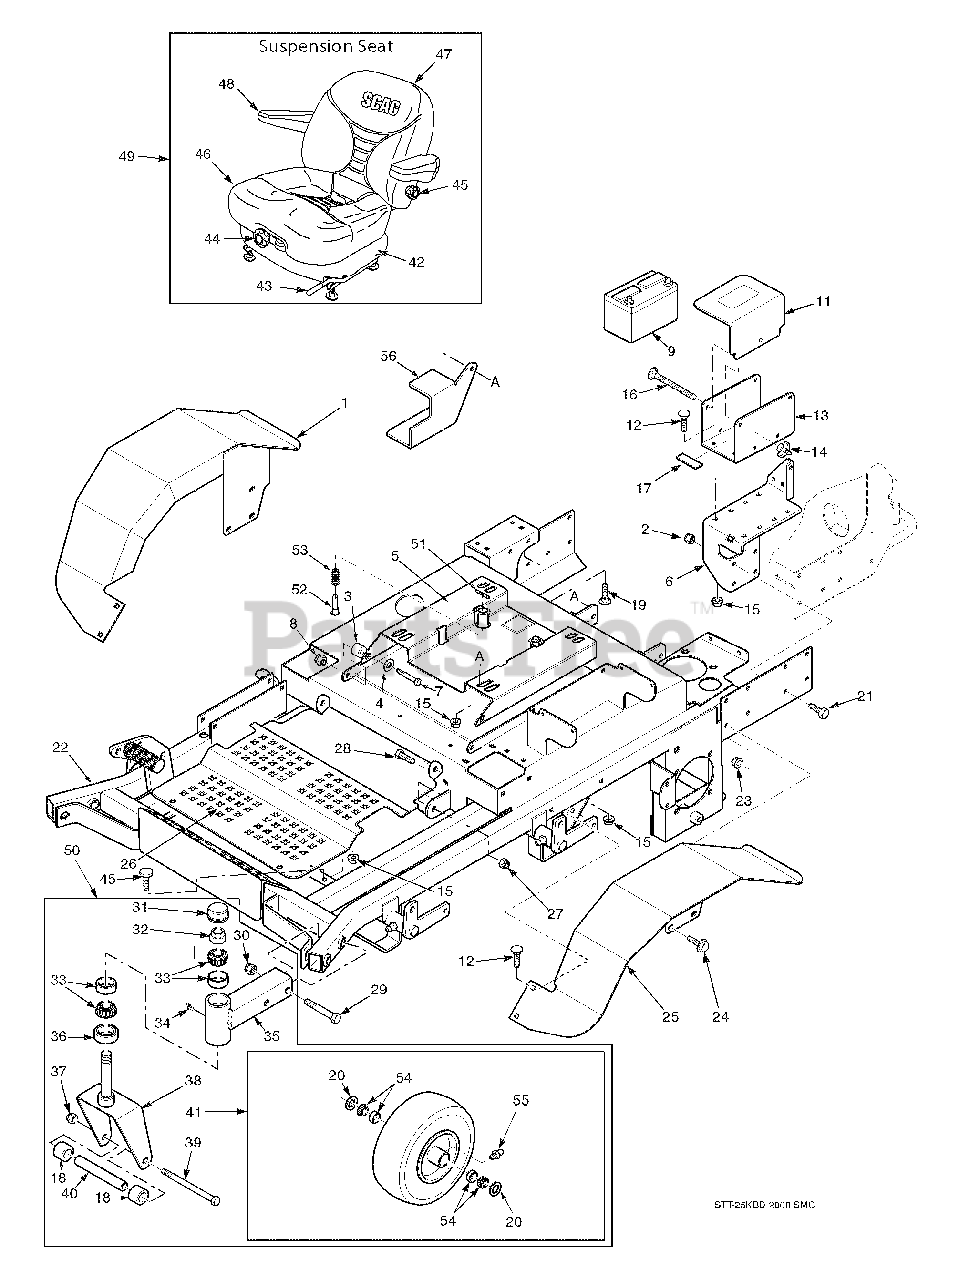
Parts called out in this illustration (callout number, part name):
1	Fender Weldment, RH
2	Nut, Elastic Stop 3/8-16
3	Spacer
4	Flatwasher, 3/8-.391 x .938 x .105
5	Seat Plate Weldment
6	Battery Box Mount
7	Bolt, Hex Head 3/8-16 x 2.0"
8	Nut, Elastic Stop 3/8-16
9	Battery
10	Pad, Battery Cover
11	Cover, Battery
12	Bolt, Carriage 5/16-18 x 3/4"
13	Plate, Battery Box
14	Wing Nut, 1/4-20 x 3/4"
15	Nut, Hex Serrated Flange 5/16-18
16	Bolt, Carriage 1/4-20 x 7-1/2"
17	Rubber Pad
18	Spacer, Caster Wheel
19	Bolt, Carriage 5/16-18 x 1"
21	Bolt, Hex Head 3/8-16 x 1"
22	Main Frame
23	Nut, Hex Serrated Flange 3/8-16
24	Screw, Hex Serrated Flange 3/8-16 x 1"
25	Fender Weldment, LH
26	Foot Plate
27	Nut, Hex Elastic Stop 3/8-16
28	Bolt, Hex Head 3/8-16 x 1"
29	Bolt, Hex Head 5/8-11 x 4"
30	Nut, Hex Elastic Stop 5/8-11
31	Cap, Grease
32	Nut, Hex Elastic Stop 1.0-14
33	Bearing W/Race
34	Plug, 1/4-28 THD Form
35	Extention Weldment, Caster 61A
36	Seal, 2.00 OD. x 1.625 Bore
37	Nut, Hex Elastic Stop 1/2-13
38	Yoke Weldment, Caster
39	Bolt, Hex Head 1/2-13 x 9-1/2"
40	Sleeve, Caster Wheel
41	Wheel Assembly
42	Shock Absorber Kit
43	Seat Adjustment, Track Set
44	Weight Adjustment Kit
45	Lumbar Kit
46	Seat Cushion Kit
47	Back Cushion Kit
48	Armrest Only
49	Suspension Seat Assembly w/seat belt
50	Caster Wheel Assy 61V
51	Roll Pin, Spring 5/32 x 3/4"
52	Pin Retainer, Spring
53	Spring, Seat
54	Bearing w/ Race
55	Grease Fitting
56	Guard, Fuel Line
